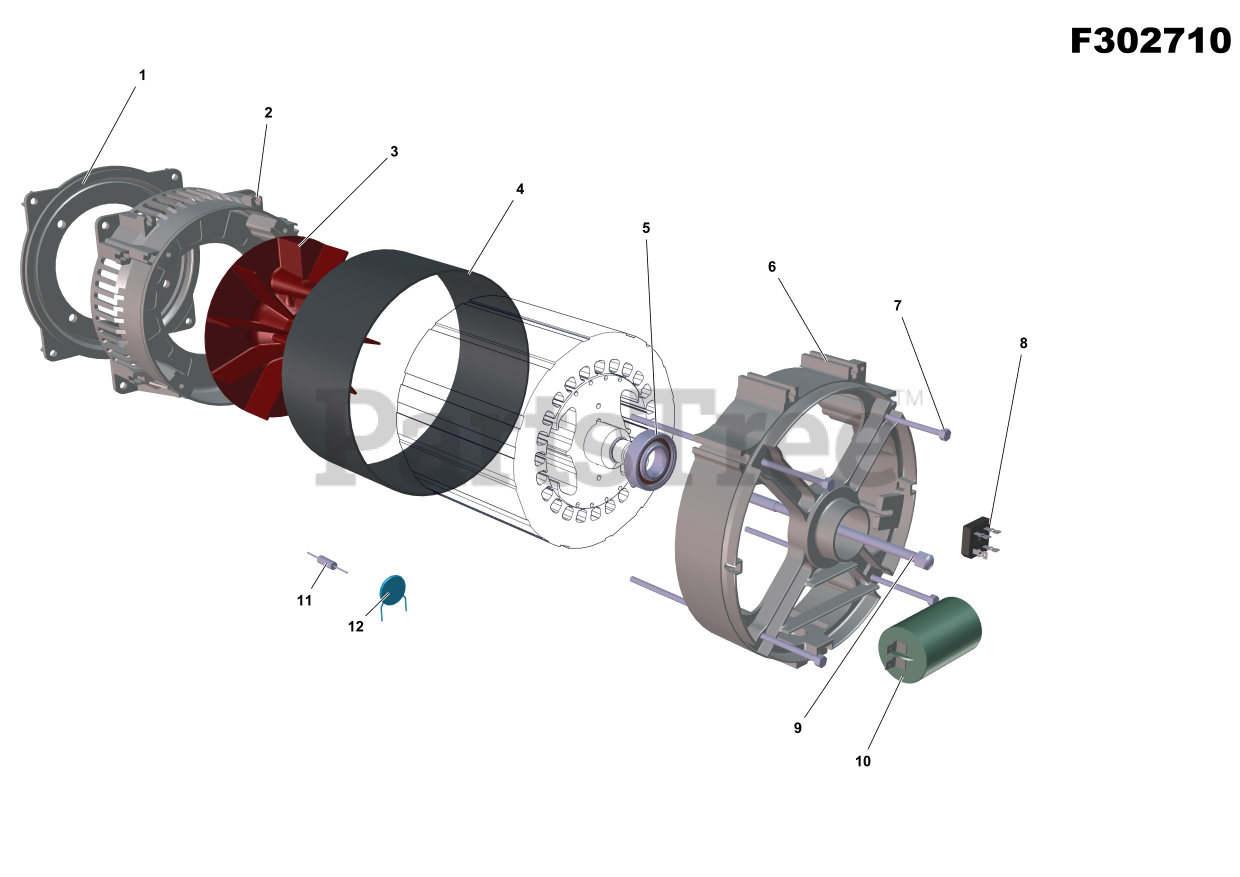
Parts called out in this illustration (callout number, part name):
2	FRONT FLANGE (S20W/B)
6	REAR FLANGE
7	COVER STAY BOLT
8	DIODES BRIDGE
9	COVER STAY BOLT
10	CAPACITOR
11	DIODE D2/125 25A
